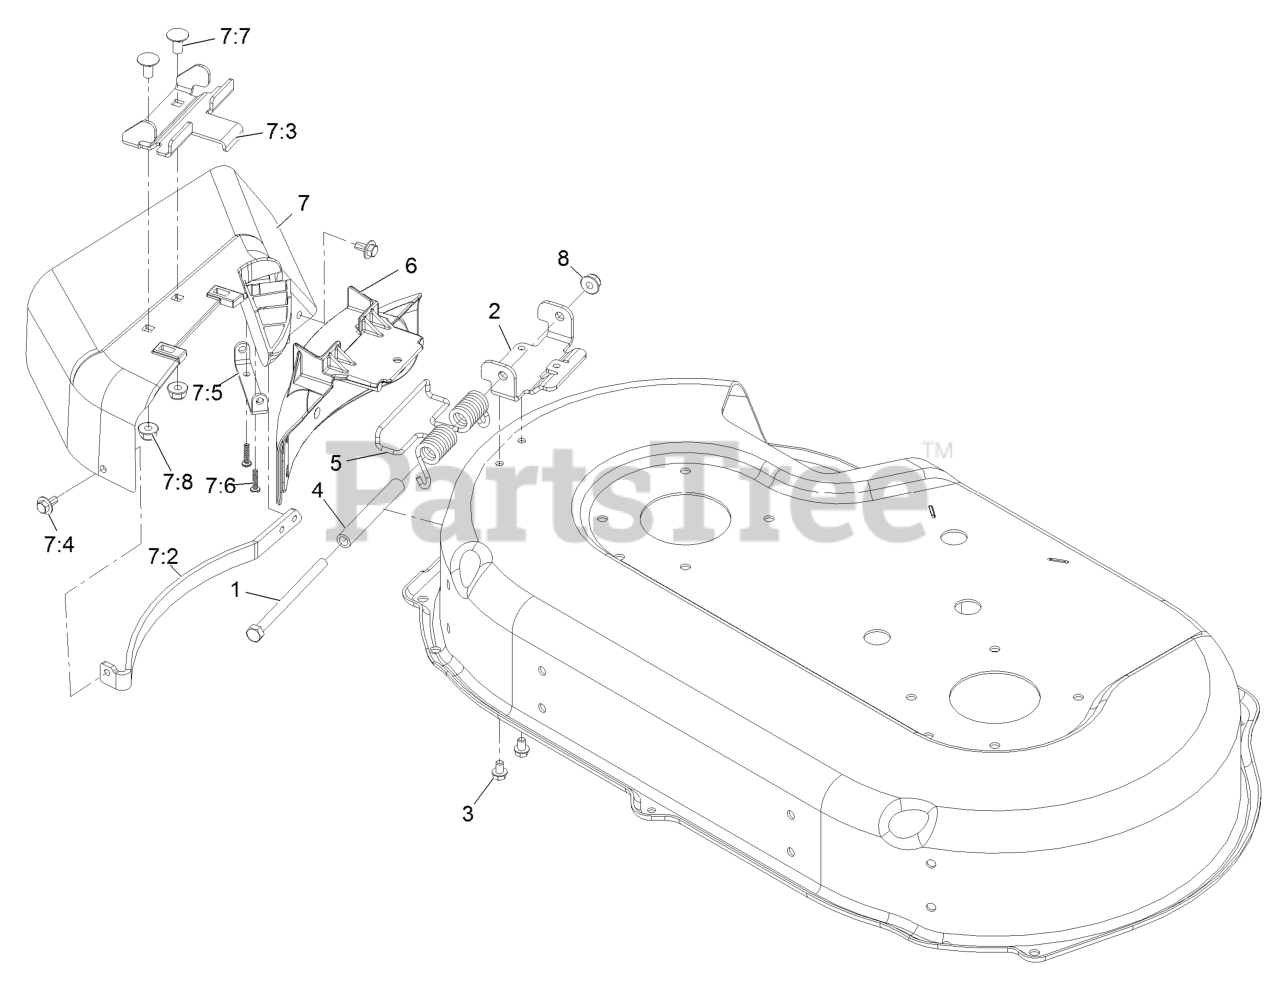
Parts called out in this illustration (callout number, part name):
1	SCREW-HH
3	SCREW-HWH
5	SPRING-TORSION
6	COVER-DISCHARGE
7	SIDE DISCHARGE CHUTE ASM
7:2	GUARD-CHUTE
7:3	BRACKET-CHUTE
7:4	SCREW-HHFTF
7:5	BRACKET-COVER
7:6	SCREW-PPH
7:7	SCREW-CARR
7:8	NUT-HF, NI
8	NUT-HF, NI
